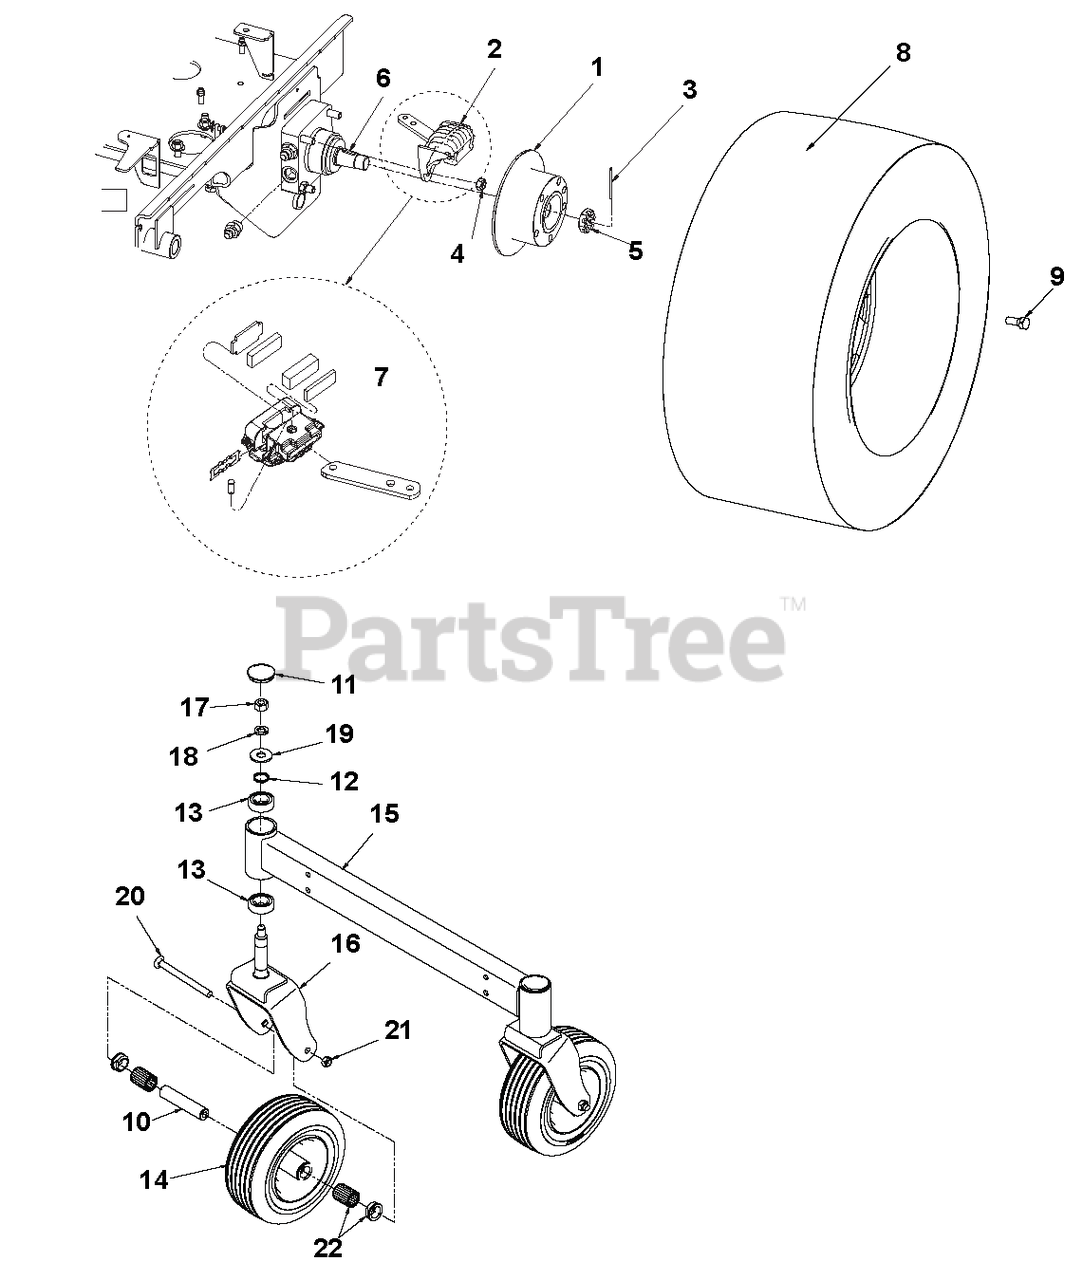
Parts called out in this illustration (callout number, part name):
1	HUB, WHEEL - 5 BOLT, 8" DISC
2	CALIPER, M15 BRAKE & BRKT CCW
2	CALIPER, M15 BRAKE & BRKT CW
3	PIN, COT .125X1.75 EXTP Y
4	LOCKNUT, 1/2-13 CROWN Y
5	NUT, 1-20 SPECIAL CASTLE S/O
6	KEY, WDRF .313X1.00-#1008 S/O
7	KIT, 3/16 DISC BRAKE PAD S/O
8	ASSY, TIRE & RIM - 23X10.50-12
8	TIRE, W/O RIM 23 X10.50-12 4PL
8	RIM, 12X8.5X.3 OFFSET SLVR S/O
9	BOLT, 1/2-20X1.00 LUG Y
10	TUBE, RD 1.00X.500X4.76
11	CAP, DUST 2.14
12	WASHER,WAVE 1.0SHAFT 1.25 BORE
13	BRG, BAL .984X2.05X.591 - 6205
14	WHEEL, FRONT 11X4X5
15	WLDT, FRNT AXLE (PAINT ARIENS)
16	WLDT, FR WHEEL FORK (ARIENS)
17	NUT, 5/8-11 STD HEX GR5 Y
18	WASHER, .625 MED SPRG LOCK Y
19	WASHER, .625 REG FLAT Y
20	BOLT, 1/2-13X6.00 CRG Y
21	LOCKNUT, 1/2-13 CROWN Y
22	KIT, BRG - 1.00 X 4.75 HUB S/O
